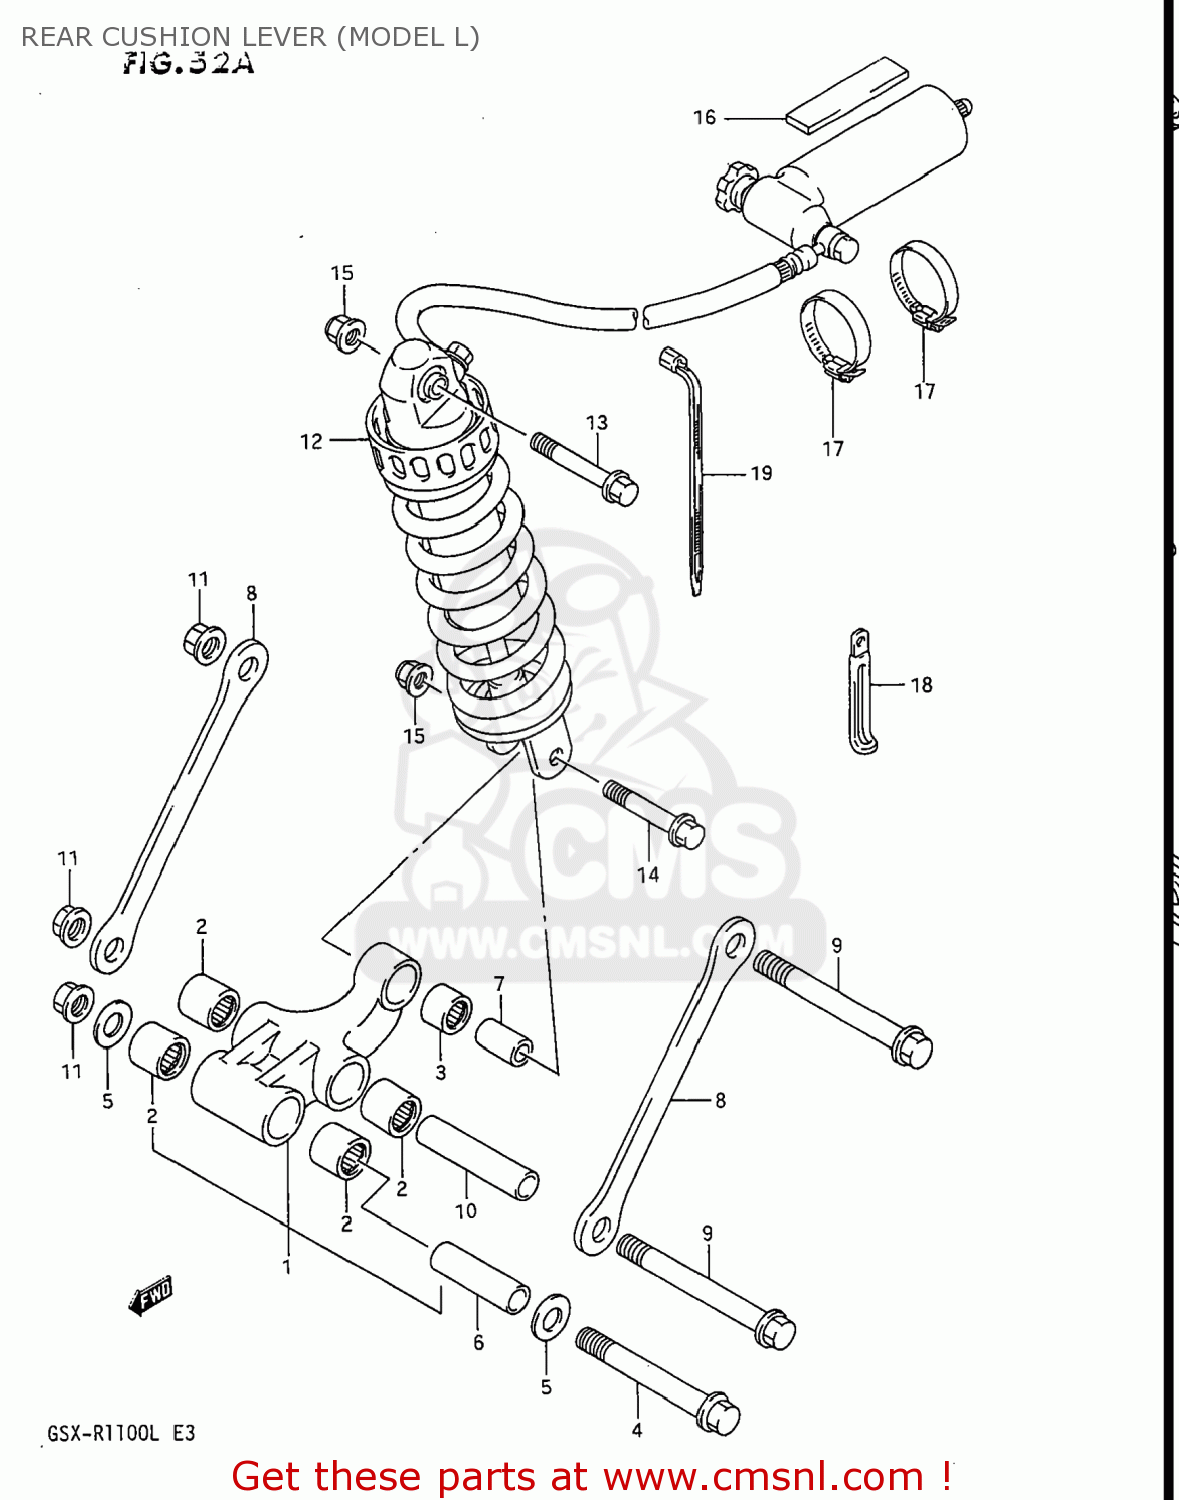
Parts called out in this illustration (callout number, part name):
1	LEVER SET,REAR CUSHION
2	BEARING(20X27X23.5)
3	BEARING(17X24X26)
4	SHAFT,RR CUSHION LEVER FR
5	WASHER
6	SPACER,RR CUSHION LEVER
7	SPACER,RR CUSHION LEVER
8	ROD,REAR CUSHION LEVER
9	SHAFT,RR CUSHION ROD
10	SPACER,RR CUSHION ROD
11	NUT
12	ABSORBER ASSEMBLY,REAR SHOCK
13	BOLT
14	BOLT(10X60)
15	NUT
16	CUSHION,RESERVOIR TANK
17	CLAMP
18	CLAMP
19	CLAMP(L:165)
